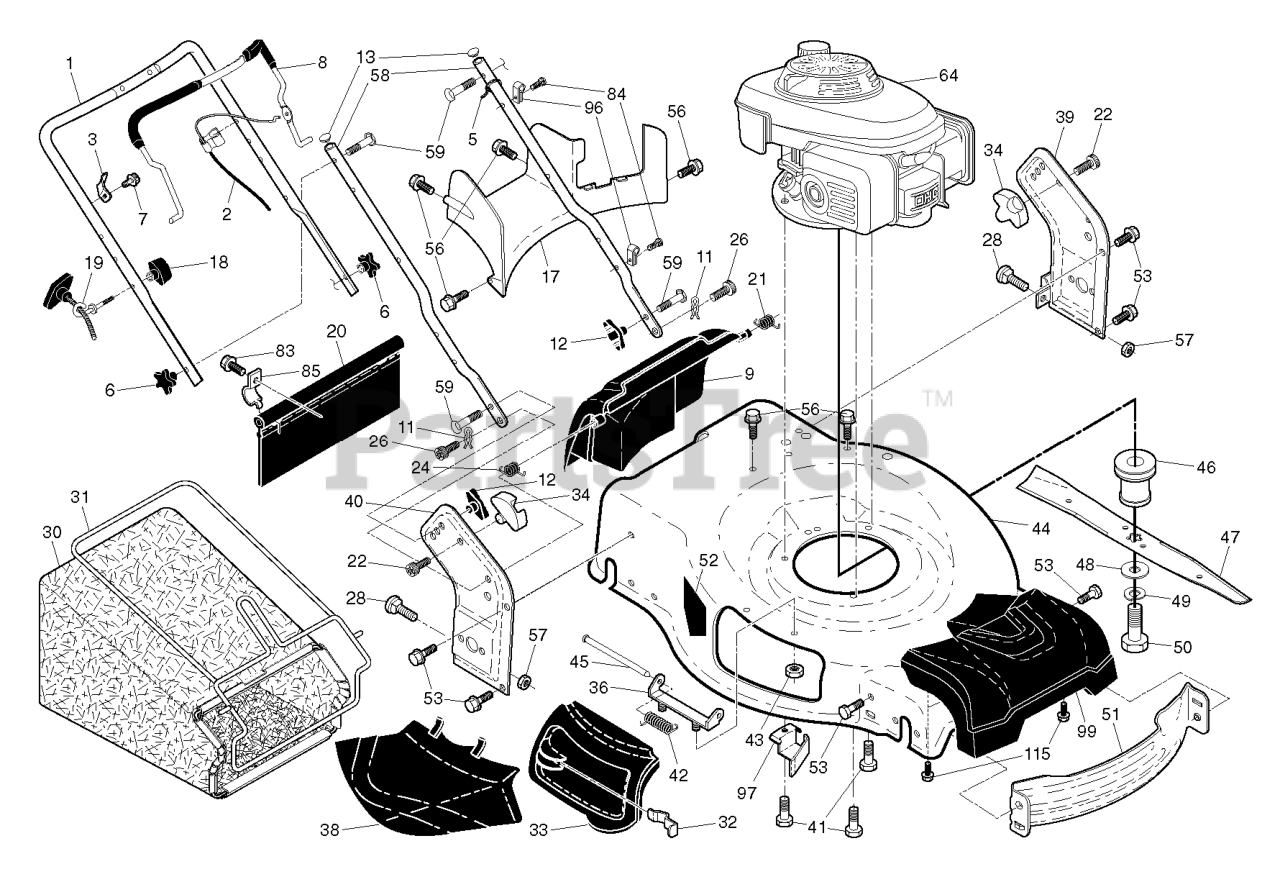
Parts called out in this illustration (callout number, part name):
1	HANDLE.UPPER.3.POS.BS.AW2.GREY
2	CABLE.MZR.50.SNAP-IN
3	BRACKET.UPSTOP.RT
6	KNOB.HANDLE.PLASTIC.STAR.BLACK
8	BAIL.OVER.MOLD.ERGO.MZR.ORANGE
9	DOOR.REAR.ASM.22+.HUSQ.FG/RGD
11	COTTER.HAIRPIN.DOOR/HANDLE.PIV
12	KNOB, DEFLECTOR
13	PLUG.PLASTIC.7/8".14-20.GAUGE
17	BAFFLE.REAR.22+RGD.AWD.PLASTIC
18	T-KNOB.NEW ROPE GUIDE
19	GUIDE.ROPE.BLK.ZINC.CHROM
20	SKIRT.REAR.22PLUS.RGD.LW(2 2MC
21	SPRING.LH.BLACK
22	SCREW.PAN.HEAD.#10
24	SPRING.RH.GRAY
26	SCREW,DOOR/HANDLE.PIVOT
28	BOLT.CARRIAGE.LN.5/16-18X.5/8
28	Bolts
30	GBAG.A361029ER.HUSQ.GRY/SIL
31	FRAME.GBAG.22+.BLK
32	LATCH.DOOR.ZINC
33	DOOR.MULCH.22 PLUS.HUSQ.GREY
34	BRACKET.ASM.HINGE.21.FWGD.
36	BRACKET.ASM.HINGE.21.FWGD.
38	DEFLECTOR.CLIPPING.22.BLACK
39	BRACKET.ASM.HANDLE.LT.22+.GREY
40	BRACKET.ASM.HANDLE.RT.22+.GREY
41	BOLT 3/8-16X1-1/8
42	SPRING.TORSION
43	NUT.HEX.FLANGE.1/4
44	HOUSING.22+.RWD.HUSQ.ORANGE
44	KIT.HSG.22+RGD.MC.WO.ORG.CESYM
45	ROD.HINGE.21
46	ADAPTER.BLADE.25MM.3MPH
47	BLADE.22PLUS
48	WASHER,HARDEN
49	LOCKWASHER
50	SCREW, HEX HD 3/8-24 X 1-3/8
51	BAFFLE.FRONT.22.PLUS
52	DANGER DECAL
53	BOLT.5/16HEX.WHS.HD
56	SCREW.HX.13X.750
57	NUT.FLANGE.5/16
58	HANDLE.LOWER.22+BT.2PC.GRY
59	BOLT, HANDLE 5/16-18X1.75
83	TAPPING SCREW
84	FASTENER.PUSH.O.250X0.783
85	BRACKET.SKIRT.22+.BZP
96	CLIP.CABLE.BLK
97	BRACKET.DRIVE.COVER.RGD.
99	COVER.ASM.FRONT.HUSQ.22+RGD
115	SCREW.HI-LO. 5/16 X 1.00
